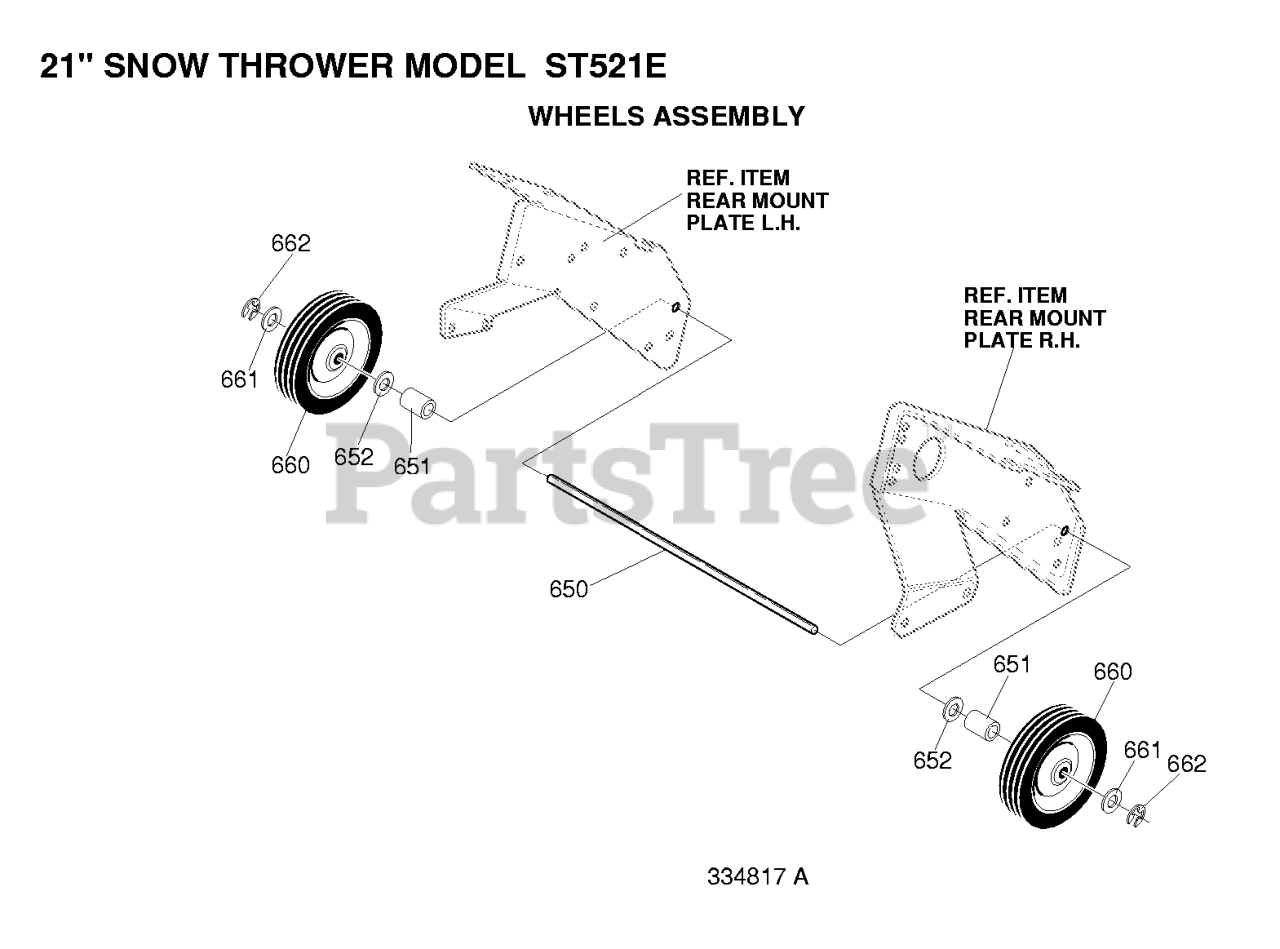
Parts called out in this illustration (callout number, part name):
650	SHAFT, AXLE 5/21 SC
651	SPACER, SLEV .407X.63X.440
652	WASHER, FLAT .406X .81X.
660	TIRE & RIM 8 X 1.75
661	WASHER, FLAT .406X .81X.
662	RETAINING RING
